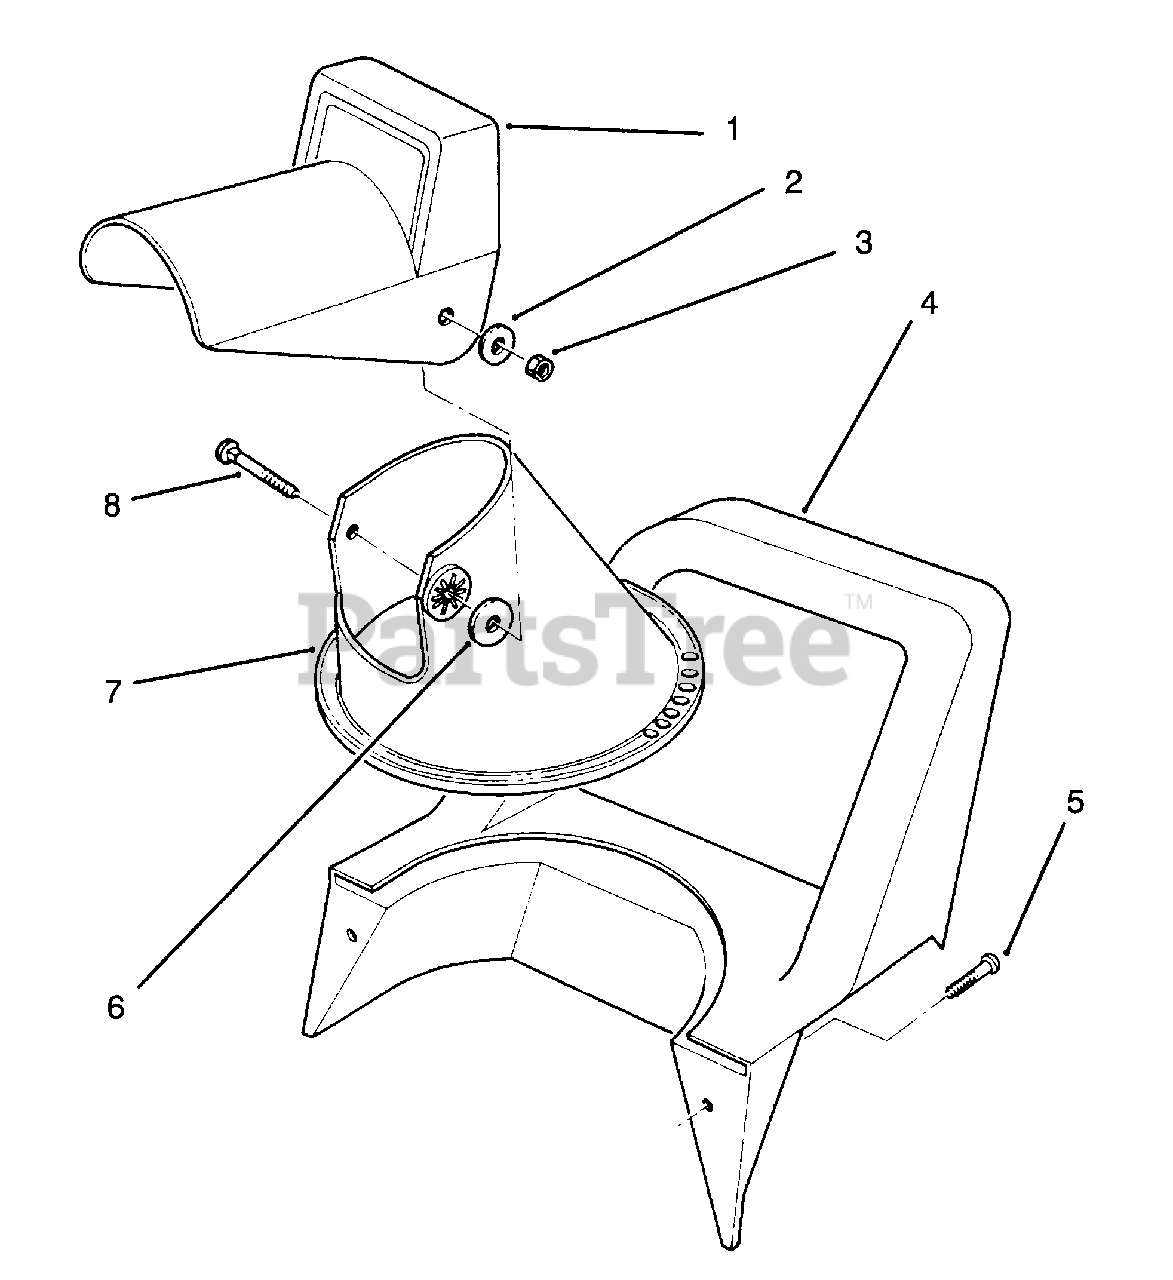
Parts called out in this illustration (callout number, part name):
1	Chute-Deflector
2	Washer-Flat
3	Nut-Lock
4	Handle-Middle
5	Screw-Pan Hd. Form.
6	Washer-Rubber
7	Chute-Lower
8	Bolt-Carriage
